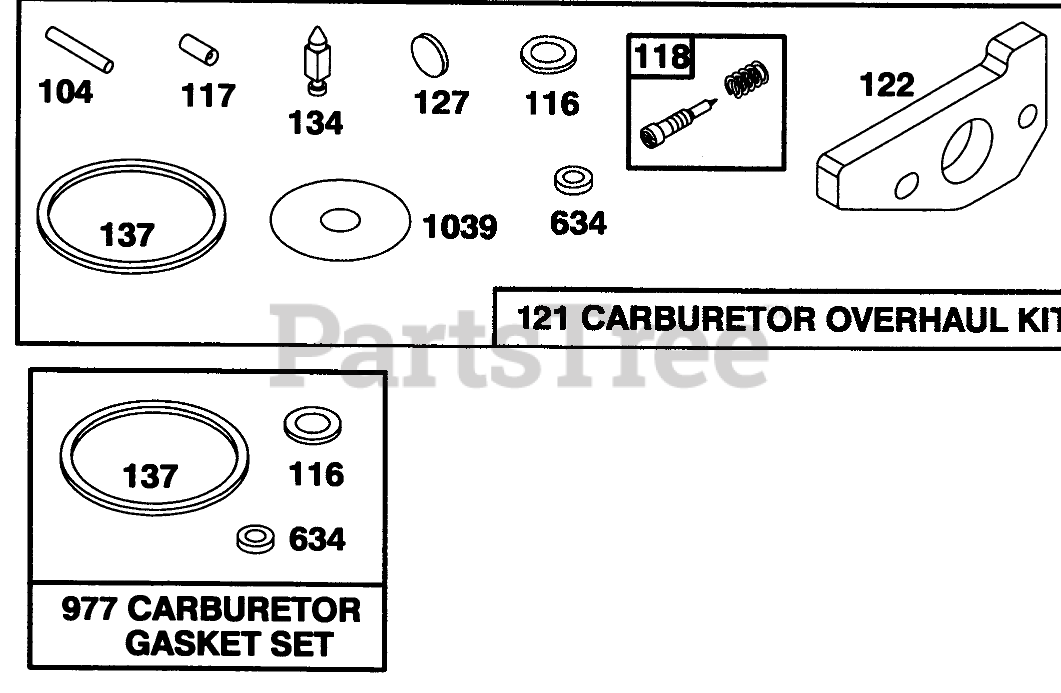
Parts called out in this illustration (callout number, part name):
104	FLOAT HINGE PIN
116	SEALING GASKET
118	VALVE KIT - NEEDLE
121	CARBURATOR OVERHAUL KIT
122	ADAPTER ASSEMBLY
134	Valve-Float (Includes Seat)
137	FLOAT BOWL GASKET
634	SEAL WASHER
977	CARBURATOR GASKET SET
1039	FLOAT LIMITER
